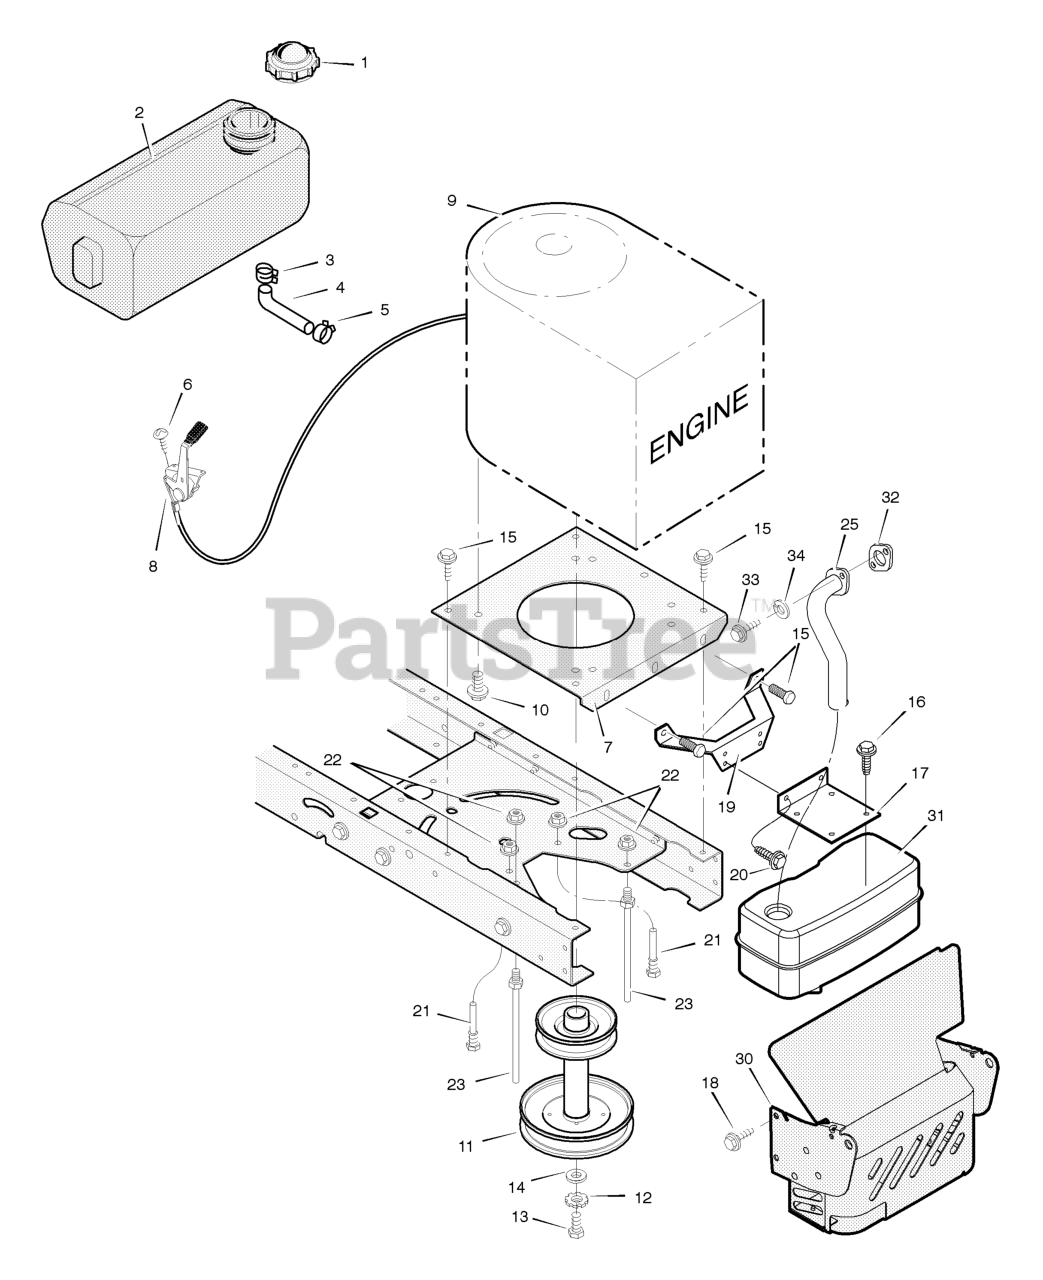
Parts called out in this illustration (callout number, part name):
1	Fuel Cap
2	TANK, Fuel 1.4 Gal.
3	Hose Clamp
4	Fuel Line (Must cut to length)
5	Hose Clamp
7	Plate, Engine
8	Throttle Control
9	Engine, Briggs & Stratton *
10	Bolt, Engine Mount
11	STACK PULLEY ASSEMBLY
12	Lockwasher
13	Bolt, Hex
17	Bracket, Muffler
19	Bracket, Muffler Mount
21	Guide, Belt
22	Nut, Flange
23	Guide, Belt
25	Exhaust Tube, Single
30	Shield, Heat
31	Muffler
32	GASKET, Exhaust
34	Washer
